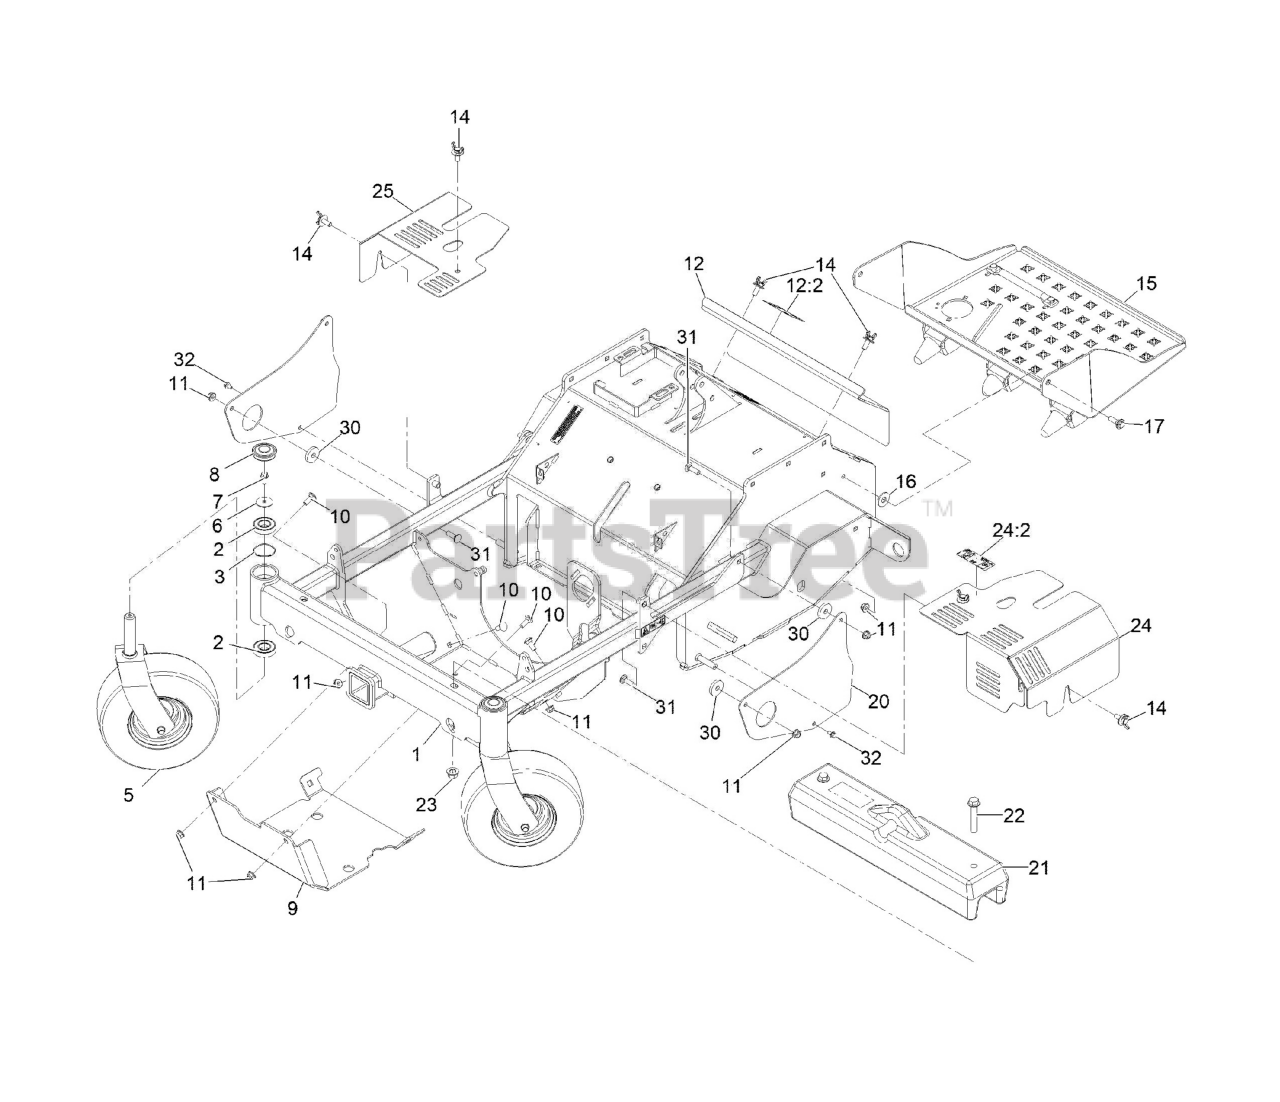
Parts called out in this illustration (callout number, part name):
1	Main Frame ASM
2	BEARING-BALL
5	Front Caster ASM
6	WASHER-FLAT
7	SCREW-HHF
8	CAP-GREASE
9	GUARD-ENGINE
10	BOLT-CARR
11	NUT-HF, NI
12	ACCESS COVER ASM
12:2	DECAL-OPERATION, TINE GRO
14	Screw-Sems (3/8-16 X 1)
15	PLATFORM ASM
16	WASHER-FLAT
17	SCREW-SHOULDER, HWH
20	Guard-Chain
21	WEIGHT-FRONT
22	SCREW-HF
23	Nut-Lock 1/2-13
24	HYDRO-COVER
24:2	DECAL-RELEASE, DRIVE
25	COVER-HYDRO
30	WASHER-CLUTCH
31	BOLT-CARR
32	SCREW-HHF
